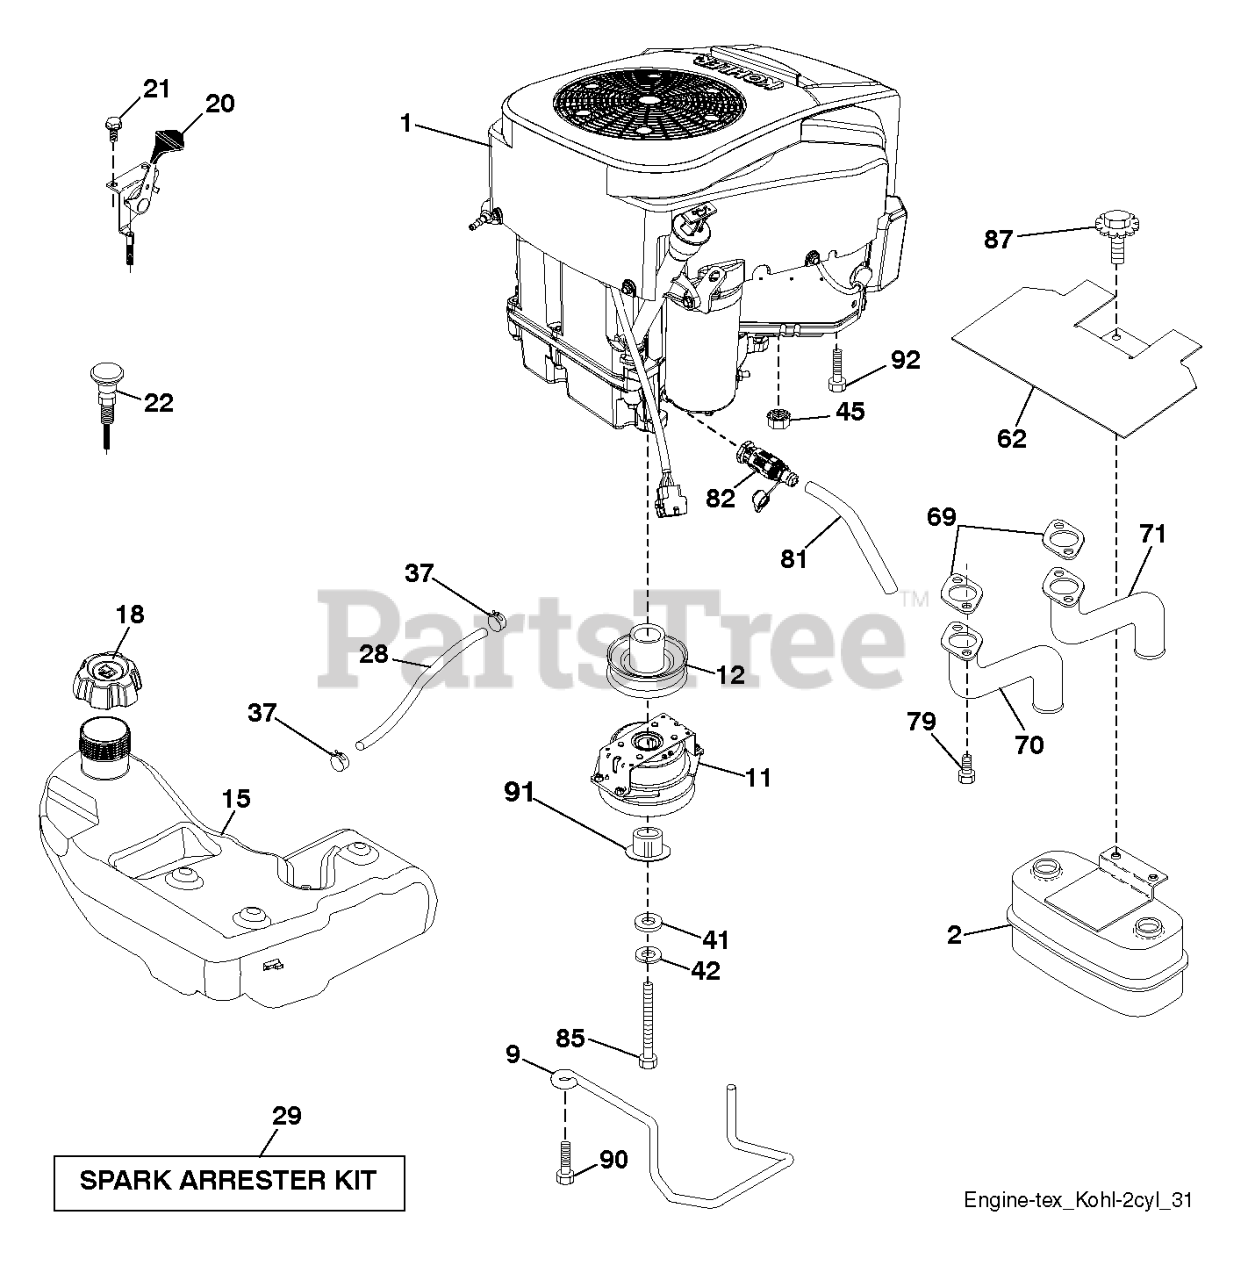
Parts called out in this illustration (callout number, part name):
2	MUFFLER.ASM.TWN.EXTNDED.DFLCTR
9	KEEPER.BELT.ENGINE.4.2
11	CLUTCH.ELECTRIC.LT.48"*
12	PULLEY.ENGINE.TUFFTORQ
15	RP_TANK.ASSY.3.GAL.EPA
18	CAP.ASM.FL.RITCH.3"E10.SYM.498
20	THROTTLE CONTROL
21	SCREW.#10 X 0.750.BOS
22	CONTROL.CHOKE.ERGO.PUSH-IN.BLA
28	LINE.FUEL.64"REAR.EMIS
29	KIT.SPARK ARRESTOR 794945 B&S
37	HOSE CLAMP
42	LOCKWASHER
45	NUT
62	SHIELD.HEAT.MUFFLER
69	GASKET.EXHAUST.KOHL.CV18-CV26
70	RP.PIPE-EXHAUST LH
71	RP.PIPE-EXHAUST RH
79	SCREW.SOCKET HD.5/16-1
81	TUBE, DRAIN OIL ASM.
82	VALUE.OIL.DRAIN
85	BOLT HEX 7/16-20X4-1/4"
87	BOLT.5/16-18UNCX3/4 W/SEMS.BLK
90	SCREW 3/8-16X1
91	BUSHING.1.375OD
92	SCREW 3/8-16X1
